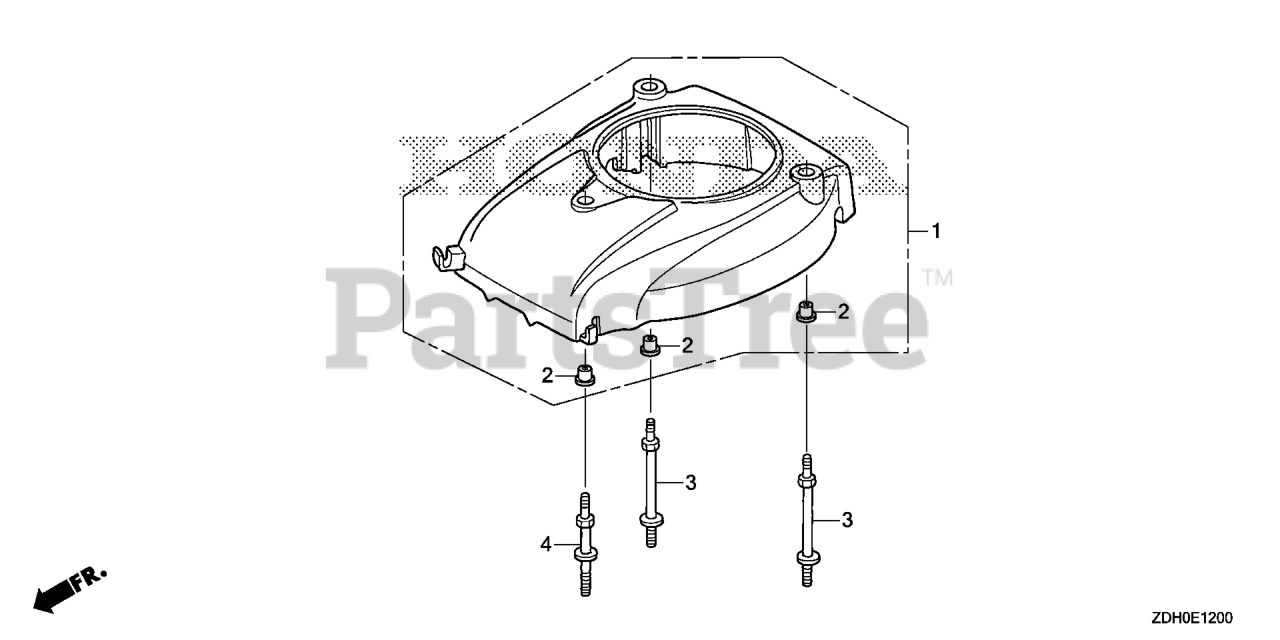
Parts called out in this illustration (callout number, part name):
1	COVER, FAN *NH1* (BLACK)
2	COLLAR, FAN COVER
3	BOLT A, STUD
4	BOLT B, STUD
